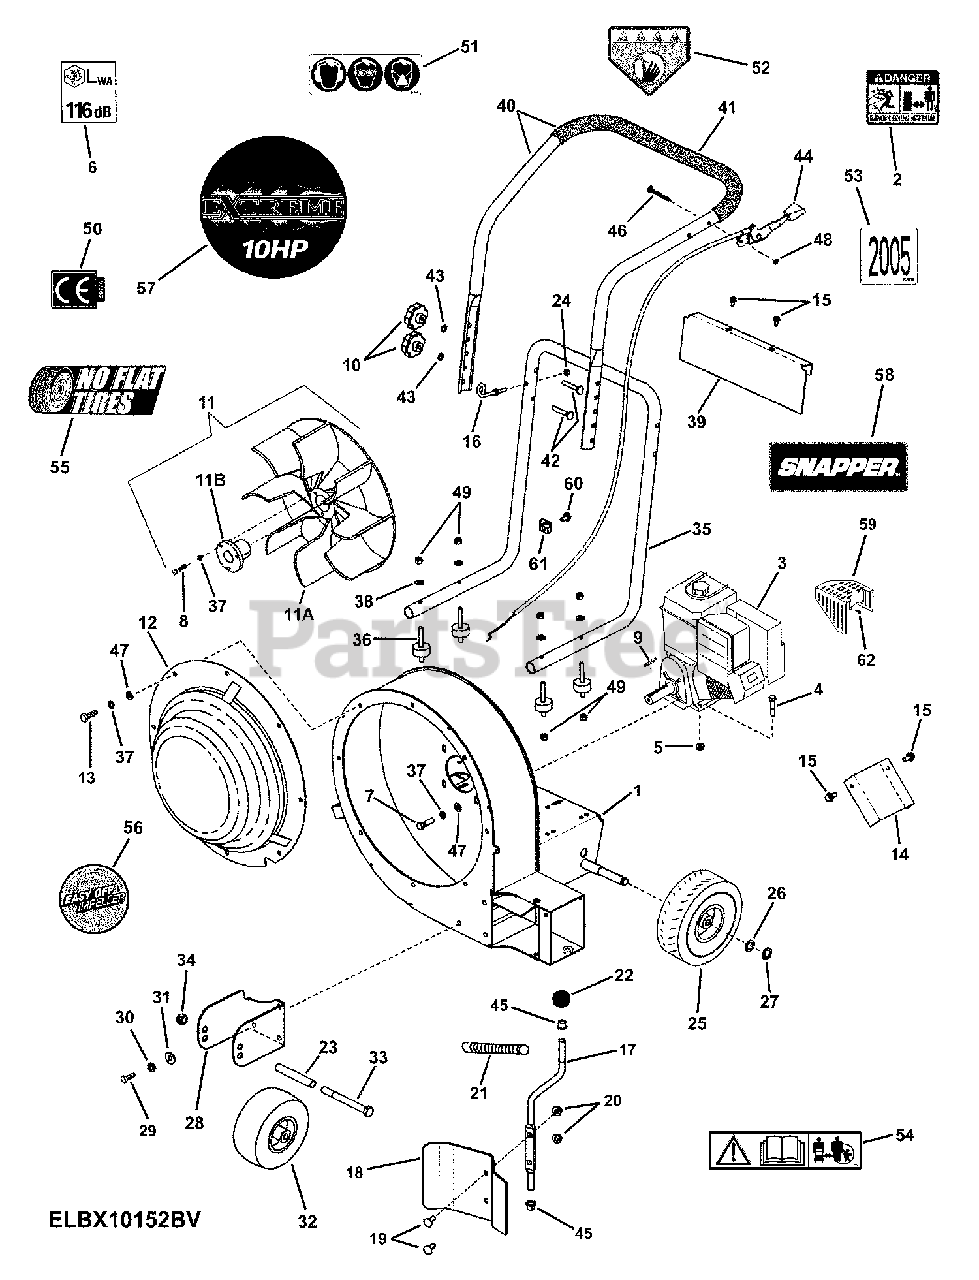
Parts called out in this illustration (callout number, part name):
1	WELDMENT, Housing- Extreme Blower
2	DECAL, Danger, Thrown Objects
3	*ENGINE, 10HP B&S Intek OHV
4	SCREW, 5/16-18 x 1-1/2" Hex Head Cap, GR 5
5	NUT, 5/16-18 Hex Flange Lock, GR 5
6	DECAL, Sound 116 dB
7	SCREW, 5/16-24 x 1" Hex Head Cap, GR 5
8	SCREW, 5/16-18 x 1-1/4" Hex Head Cap, GR 5
9	KEY, 1/4" Square x 1-7/16"
10	KNOB, 5/16-18 Fluted
11	ASSY, 15" 9 Blade Impeller
11A	IMPELLER, 15" O.D. Cast
11B	HUB, Taper-Lok, Type 1 - P1 x 1.125 (1.938 OAL)
12	WELDMENT, Intake Baffle- Extreme
13	SCREW, 5/16-18 x 3/4" Hex Head Cap, GR 5
14	DEFLECTOR, Side Air
15	SCREW, 5/16-18 x 5/8" Hex Washer Self-Tap
16	ROPE GUIDE (1/4-20 thread)
17	ROD, Door Front/Side Discharge
18	DOOR, Forward Air Control
19	SCREW, 1/4-20 x 3/4" Short Square Neck Carriage, GR 5
20	NUT, 1/4-20 Hex Flange Lock, GR 5
21	SPRING, Extension
22	KNOB, #230 Dimco (3/8-16 thread)
23	SLEEVE, Axle
24	NUT, 1/4-20 Hex Center Lock, GR 5 or B
25	ASSY., Wheel & Tire 410/350-4 "Sawtooth"
26	WASHER, .64 x .99 x .05 Flat
27	RING, External Retaining
28	BRACKET, Front Wheel Mounting
29	SCREW, 3/8-16 x 1" Hex Head Cap, GR 5
30	WASHER, 3/8" Split Lock
31	WASHER, 3/8" Flat
32	ASSY., Tire & Wheel 9 x 350-4 Smooth
32A	**RIM, One-Piece Steel, Gray
32B	**TIRE, 9 x 3.50-4, 4 Ply, Smooth
32C	**BEARING, Roller
32D	**BALL BEARING, Flanged
32E	**VALVE, Air
32F	**GREASE FITTING, 45-Degree
33	BOLT, 1/2-13 x 5" Hex Head Cap
34	NUT, 1/2-13 Hex Center Lock, GR 5
35	HANDLE, Lower Folding- Wide- Blower
36	MOUNT, Vibration (5/16-18 threads, both ends)
37	WASHER, 5/16" Split
38	WASHER, 5/16" Curved
39	DASH PANEL, Blower- Wide
40	ASSY., Upper Handle & Grip
41	GRIP, 1.0 x 21-1/2" Foam
42	BOLT, 5/16-18 x 2" Curved Head Square Neck, GR 2
43	WASHER, 5/16" Internal Tooth Lock
44	THROTTLE CONTROL, B&S, 35.00/1.62
45	BEARING, 3/8" Clip
46	SCREW, 1/4-20 x 2" Hex Head Cap, GR 5
47	WASHER, .34 x .69 x .08 Flat
48	NUT, 1/4-20 Hex Nyloc
49	NUT, 5/16-18 Hex Nyloc
50	DECAL, Euro Community (CE)
51	DECAL, Personal Protection
52	DECAL, Danger, Cut Finger (Euro)
53	DECAL, 2005 Year of Manufacture
54	DECAL, Caution, Symbols
55	DECAL, "No Flat Tires"
56	DECAL, Easy Off Impeller
57	DECAL, 10HP Extreme- Euro- Generic
58	DECAL, SNAPPER (Panel)
59	HEAT SHIELD, B&S 9 & 10 HP Intek
60	SCREW, Casing Clamp
61	CLAMP, Casing- Briggs Intek
62	SCREW, #8-18 Self-Tap
